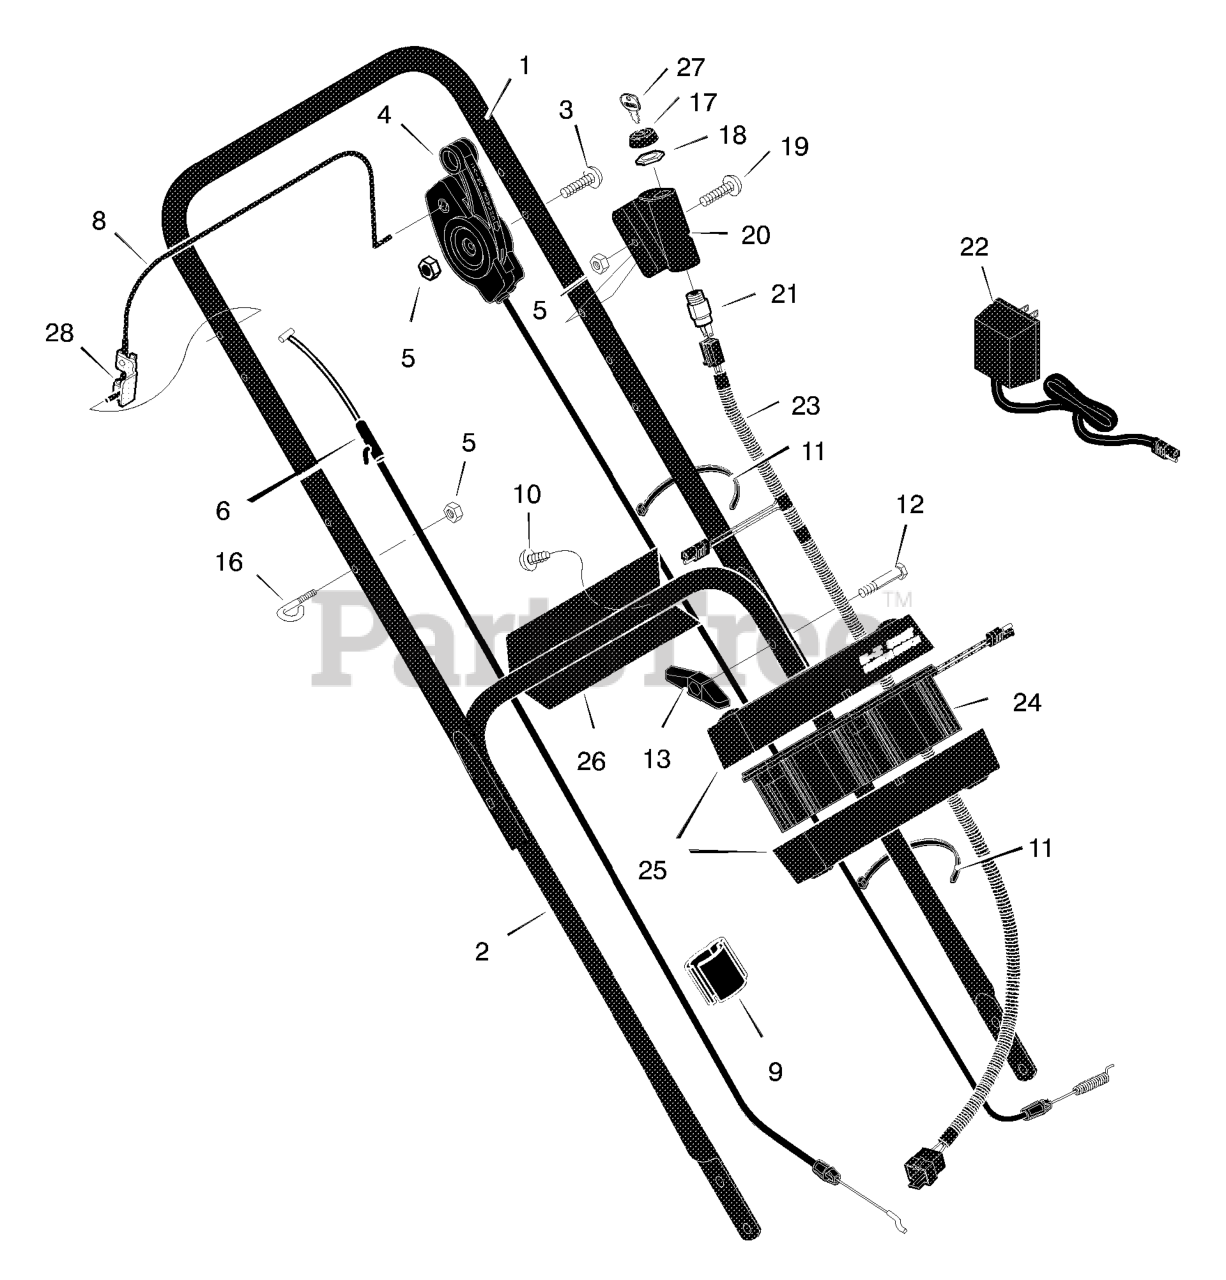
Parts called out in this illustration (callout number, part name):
1	Handle, Upper (Black)
2	Handle, Lower (Black)
4	Control, Drive
5	Locknut
6	Cable, Stop
8	Lever, Stop
9	Fastener, Single Cable
11	Tie, Cable
13	Knob
16	Guide, Rope
17	Cap
18	Nut
20	Cover, Ignition
21	Switch Ignition & Key
22	Charger, Battery
23	Harness, Wiring
24	Battery
25	Case, Battery
26	Bracket, Battery
27	Key, Ignition
28	Bracket, Stop Lever
